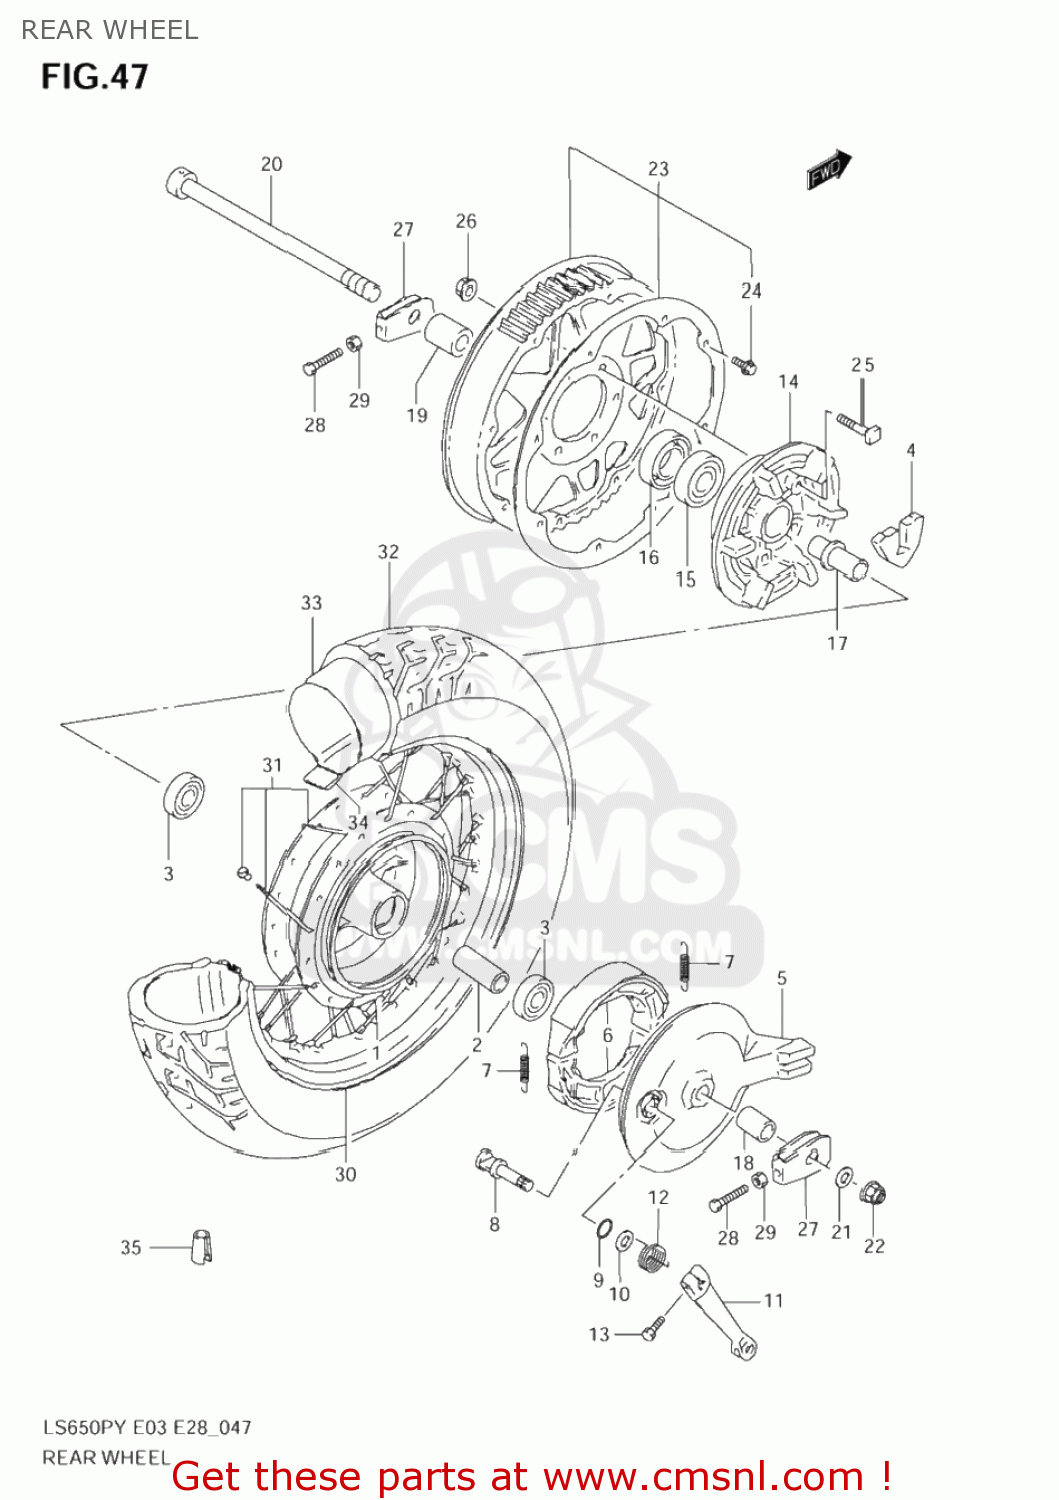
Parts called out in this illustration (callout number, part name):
1	HUB,RR WHEEL
2	SPACER(17.5X25X70)
3	BEARING
4	ABSORBER,RR HUB SHOCK
5	PANEL,RR BRAKE ANCHOR
6	SHOE SET,BRAKE (NAS)
7	SPRING,BRAKE SHOE
8	CAM,BRAKE
9	O RING(D:2.4,ID:14.8)
10	WASHER(15.5X24X1.6)
11	LEVER,RR BRAKE CAM
12	SPRING
13	BOLT. FRONT
14	DRUM,RR SPROCKET MOUNTING
15	BEARING(25X62X17)
16	SEAL,OIL(33X62X7)
17	RETAINER,RR SPROCKET DRUM
18	SPACER(17X28X22.3)
19	SPACER(17X33X35.3)
20	AXLE,RR
21	WASHER(17X30X3.2)
22	NUT
23	SPROCKET,REAR (NT:68)
24	BOLT
25	BOLT(10X40)
26	NUT
27	ADJUSTER,BELT
28	BOLT(8X43)
29	NUT
30	RIM,RR WHEEL WM(2.75X15 M/C)
31	SPOKE SET,RR WHEEL
32	TIRE,RR(140/80-15M/C 67H)
33	TUBE ASSY,WHEEL INNER
34	PROTECTOR
35	BALANCER,WHEEL
